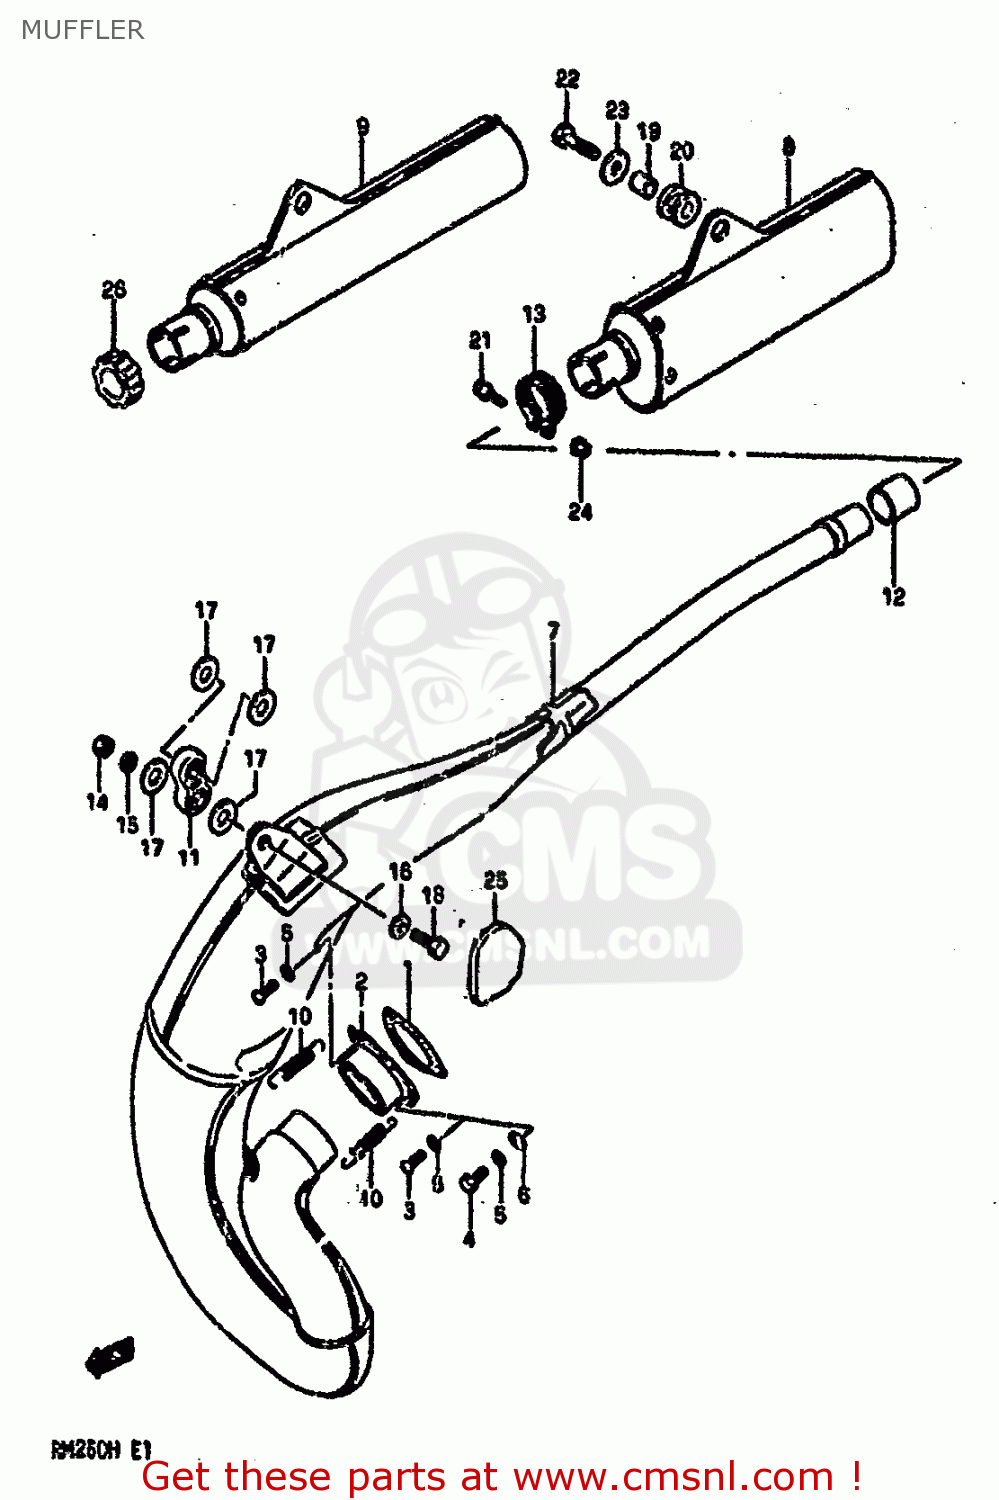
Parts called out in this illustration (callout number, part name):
1	GASKET,EXHAUST PIPE (MCA)
2	FLANGE,EXHAUST PIPE
3	SCREW
4	BOLT(6X20)
5	WASHER,LOCK
6	WASHER(6X10X2)
7	MUFFLER,1ST
8	MUFFLER,2ND
9	MUFFLER,2ND
10	SPRING
11	DAMPER,MUFFLER
12	CONNECTOR,MUFFLER
13	CLAMP,MUFFLER 2ND
14	NUT 8MM
15	LOCK WASHER
16	WASHER
17	WASHER(13X28X1.6)
18	BOLT(8X32)
19	SPACER(8.4X12X13)
20	CUSHION
21	BOLT
22	BOLT
23	WASHER (8.5X29X1.6)
24	NUT 6MM
25	CUSHION,SPACER
26	CUSHION
